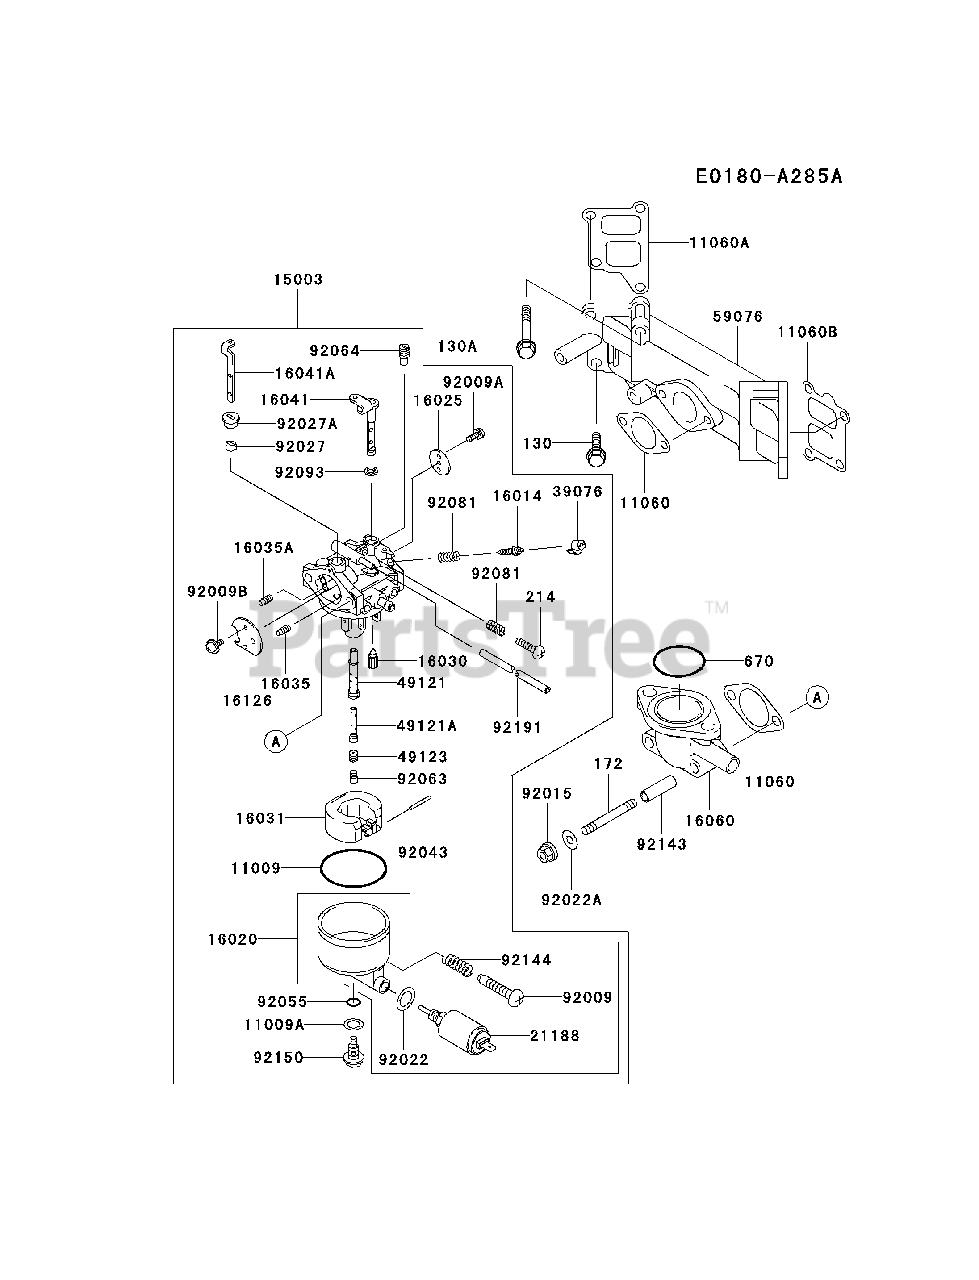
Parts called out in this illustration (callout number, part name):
130	BOLT-FLANGED
130A	BOLT-FLANGED
172	BOLT-STUD
214	SCREW-PAN+-
670	O RING
